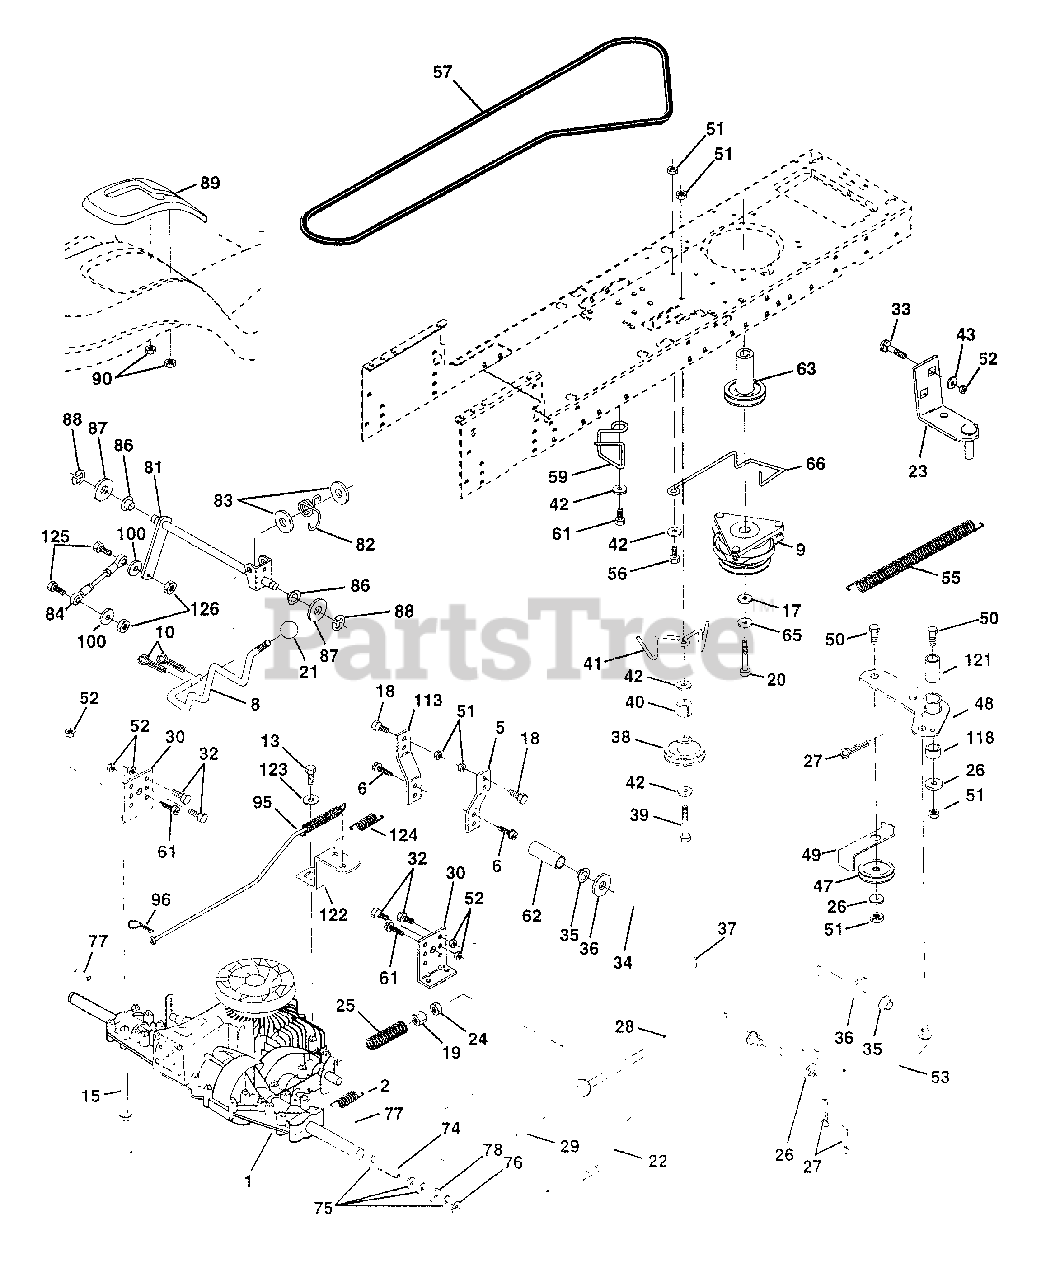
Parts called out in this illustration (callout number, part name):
1	Transaxle
2	Spring, Return Brake
5	Strap Torque
6	Screw Thdrol 5/16-18 x 3/4
8	Rod Shift Hydro LT
9	Clutch Elect
10	Pin Cotter 1/8 x 1 CAD
13	Bolt 1/4-28 Unf Gr. 8 W/Patch
15	Bolt Hex Flghd 5/16-18 Gr. 5
17	Washer 1-1/2OD x 15/32 ID x .250
18	Bolt Fin Hex 3/8-16 Unc x 1 Gr. 5
19	Nut Lock Hex W/Wsh 3/8-16 Unc
20	Bolt Hex 7/16-20 x 4-1/4 5 Ga. 1.38
22	Rod, Brake
23	Bracket Asm Mtg. CI
24	Nut, Hex Jam 3/8-16 Unc
25	Spring, Brake Rod
26	Washer
27	Pin Cotter 1/8 x 3/4 CAD.
28	Rod, Parking Brake
29	Cap, Parking Brake
30	Bracket, Transaxle
32	Bolt Hex Hd 5/16-18 Unc x 3/4
33	Bolt Rd Hd Sqnk 5/16-18 Unc x 3/4
34	Shaft, Foot Pedal
35	Bearing, Nylon
37	Pin, Roll
38	Pulley, Idler, Flat
40	Spacer, Split
41	Keeper, Belt, Idler
42	Washer 13/32 x 13/16 x 12 Gauge
43	Washer 11/32 x 5/8 x 12 Ga.
47	Pulley, Idler, V-Groove
48	Bellcrank Assembly
49	Retainer, Belt
50	Bolt
51	Nut Crownlock 3/8-16 UNC
52	Nut, Crownlock 5/16-18 Unc
53	Link, Clutch
55	Spring, Return, Clutch
56	Bolt Hex 3/8-16 x 1-1/4
57	V-Belt, Ground Drive
59	Keeper, Center Span
61	Screw Thdrol. 3/8-16 x 3/4 Ty. TT
62	Cover, Pedal
63	Pulley, Engine
65	Washer
66	Keeper Belt Engine
74	Spacer, Axle PVST
75	Washer 25/32 x 1-1/4 x 16 Gauge
77	Key, Square
78	Washer 25/32 x 1-5/8 x 16 Gauge
81	Shaft Asm. Cross Hydro
82	Spring Torsion T/A
83	Washer 17/32 x 3/4 x 16 Ga.
84	Rod, Tie PVST 20"
86	Bushing Rod Strig. 629/632 ID
87	Washer 21/32 x 1-1/4 x 16 Ga.
88	Ring Klip #5304-62
89	Console, Shift
90	Nut Self-Thd Wsh-Hd 1/4 Zinc
95	Rod Asm Bypass PVST
96	Retainer Spring 1" Zinc/Cad
100	Washer 11/32 x 3/4 x 16 Ga.
113	Strap Torque LH LT
118	Spacer Bellcrank
121	Nyliner Clutching STL
122	Plate Bypass PVST
123	Washer 9/32 x 5/8 x 16 Ga.
124	Spring Return PVST
125	Bolt Fin Hex 5/16-18 Unc x 1
126	Nut Lock 5/16-18 Unc
